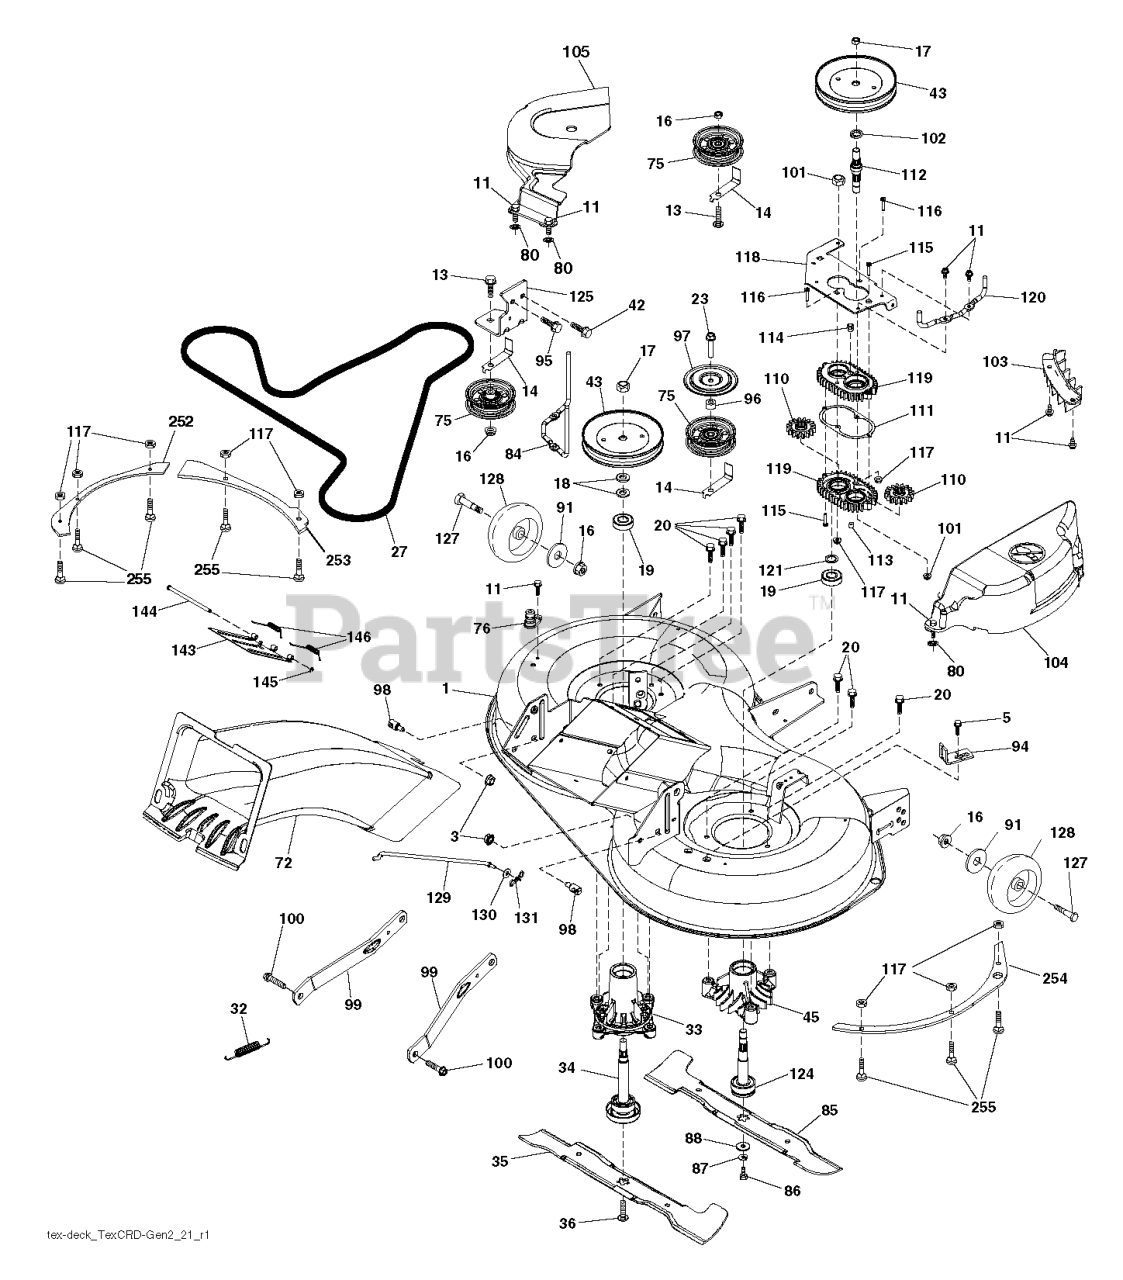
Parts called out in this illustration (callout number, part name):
1	DECK.SVC.WLDT.97EL.TCRD.EZ.498
3	NUT LOCK HEX FLANGE 5/16-18
5	BOLT.5/16HEX.WHS.HD
11	SCREW.1/4-20X5/8
13	BOLT.3/8-16X1.50
14	KEEPER, BELT IDLER
16	NUT LOCK FLG 3/8-16 UNC
17	NUT.FLANGE.LOCK.TOP
18	WASHER.SPACER.MANDREL
20	SCREW, WASHER HEAD
23	SCREW LT
27	BELT 97CM ELECTRIC
32	SPRING 107CM & 97CM ELECTRIC D
33	RP.HOUSING.MANDREL.4PT.
34	SHAFT.ASM.MDRL.N/GREASE.38
35	BLADE.3N1.LH.CRD.97
36	BOLT.WASHER.ASM.7/16-2
42	SCREW
43	PULLEY.MANDREL.5.0.PD.38"
45	HOUSING.MANDREL.44/46" VENT
72	CHUTE.107/97.TEX.GEN2.TRIMMED
75	FLAT IDLER PULLEY
76	PORT.WASHOUT
80	PALNUT 1/4
84	BELT KEEPER.MANDREL.38"COATED
85	BLADE.3N1.RH.CRD.97
86	BOLT.3/8-24X1.25GR8. LHTHRD
87	LOCKWASHER
88	WASHER.BLADE
91	WASHER
94	BRKT.CLUTCH.CABLE
95	SCREW, 3/8-16X3/4
96	SPACER
97	PROTECTOR
98	STUD.FASTNER.W/ANTI-ROTATE
99	ARM.SUSPENSION.MOWER.R
100	BOLT.SHOULDER
101	NUT.CROWNLOCK.9/16 -18.UNC
102	SPACER BEARING
103	GUARD GUARD FRONT VENT
110	CRD.SPUR.GEAR
111	GASKET GASKET GEARCASE
112	SHAFT SHAFT. CRD GEARCASE ADAP
113	PLUG PLUG OIL
114	VALVE VALVE RELIEF
115	SCREW
116	BOLT.CARIGE.SS.1/4-20X1.75GR5
117	NUT T
118	ARM ARM CLUTCHING
119	GEARCASE GEARCASE SUBASM
120	BRACKET KEEPER BELT RH
121	WASHER WASHER
124	MANDREL SHAFT NON/GREASE
125	BRACKET BRACKET IDLER CHASSES
127	BOLT.SHOULDER.3/8-16X3-5/8.
128	RP WHEEL. GUAGE RALLY
129	ROD ROD. SWAY CRD GEN II
130	WASHER
131	PIN.COTTER.5/16.BOW TI
143	DOOR
144	PIN PIN.HINGE
145	E-RING.5/16"
146	SPRING SPRING: EZ MULCH DOOR
255	RHSNB, 1/4-20 X 1, GR5
